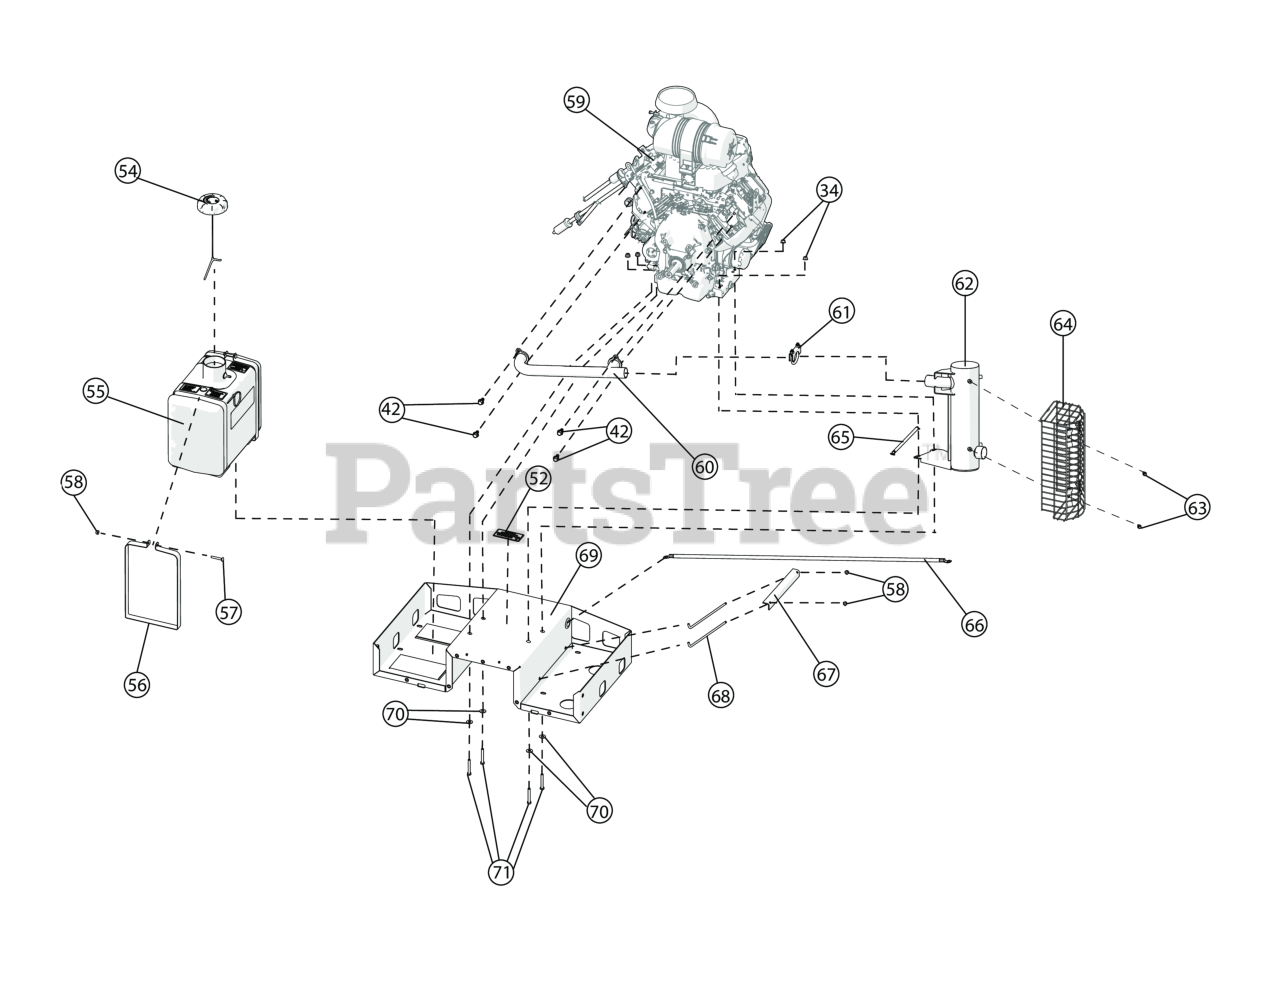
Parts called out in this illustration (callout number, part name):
34	NUT-HEX-NYLK, FLG .3125-18 ZP
42	PROVIDED WITH ENGINE
52	LABEL WARNING SECURE
54	CAP, CARB/EPA 3.500"
55	TANK & CAP ONLY - SIX GALLON 2.500" NECK
56	CLAMP, TANK FUEL
57	BOLT CARRIAGE 1/4-20 X 1 3/4 Z/P
58	NUT-HEX-NYLK, FLG .250"-20 ZP
59	ENGINE 29HP HORZ. SHAFT B&S
60	MANIFOLD DL35
61	CLAMP MUFFLER DL35
62	MUFFLER DL29/37
63	SCREW MUFFLER DL35
64	GUARD MUFFLER DL35
65	CABLE BATTERY BLACK 20"
66	CABLE BATTERY 36"
67	BRACKET BATTERY
68	ROD BATTERY HOLD DOWN
69	ENGINE 29HP HORZ. SHAFT B&S
70	WASHER 5/16" FLATWASHER Z/P
71	SCREWCAP 5/16"-18X2 1/4" HCS ZP
